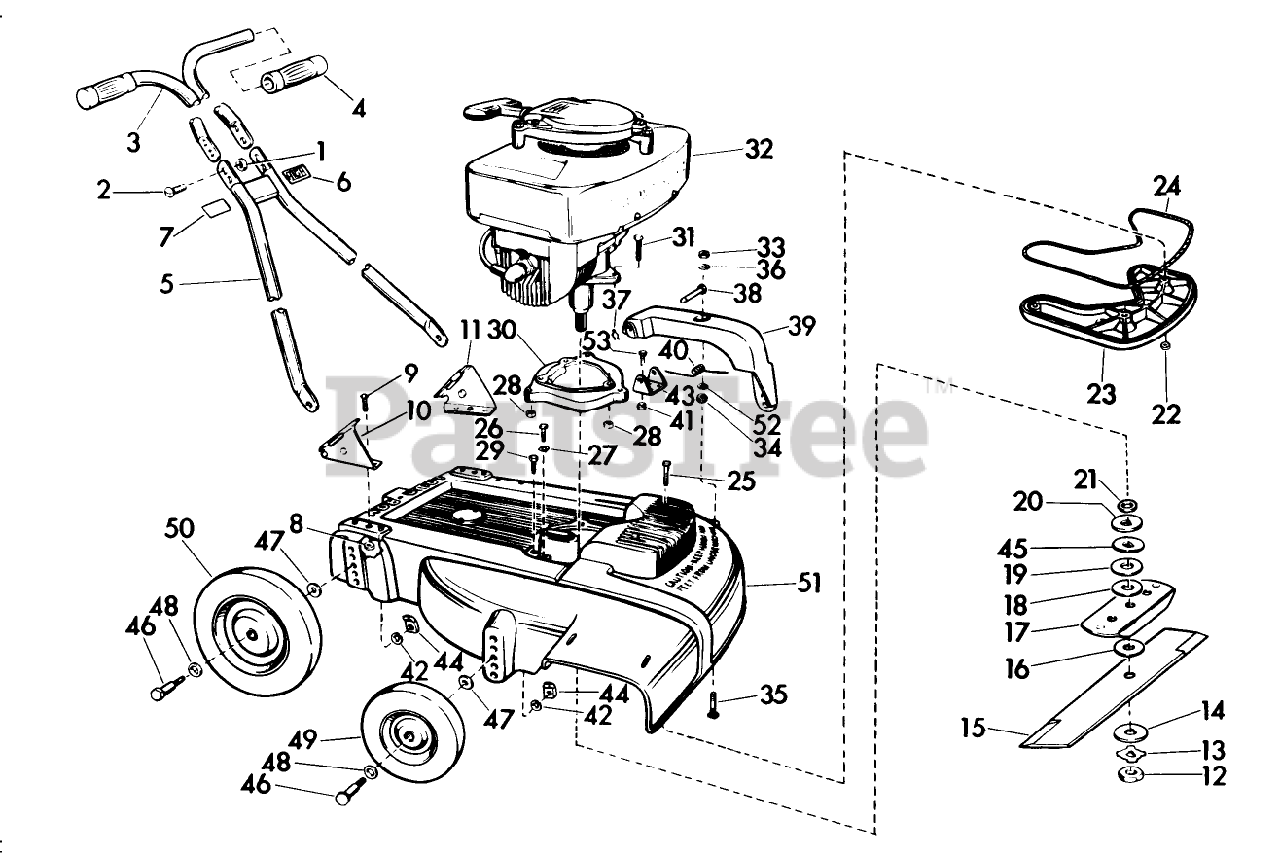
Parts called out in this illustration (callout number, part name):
1	STOP NUT
6	Decal-Handle "High"
7	Decal-Handle "Low"
12	Nut-Blade
14	Washer-Steel "D" Hole
15	Blade-21"
19	BLADE WASHER
20	Washer-Steel "D" Hole
22	LOCKNUT E
23	Muffler
25	Bolt-Muffler, Long
26	Bolt-Muffler
27	Gasket-Muffler Bolt
29	Screw-Sub Base Mounting
30	Sub Base
31	Bolt-Engine Mounting
33	STOP NUT
34	Nut-Level-Ride Bolt
35	Bolt-Level-Ride Arm
36	Washer-Level Ride Arm
37	Hair Pin-Level Ride Arm
38	Pin-Level Ride Arm
39	Arm-Level Ride
40	Spring-Level-Ride Arm
41	STOP NUT
42	WASHER, LOCK
43	Bracket-Level Ride Arm
45	Washer-Steel "D" Hole
51	Housing-18" Model 5210
51	Housing-21" Model 7210
52	Washer-Level Ride, Fiber
53	Screw-Level-RideArm Bracket
